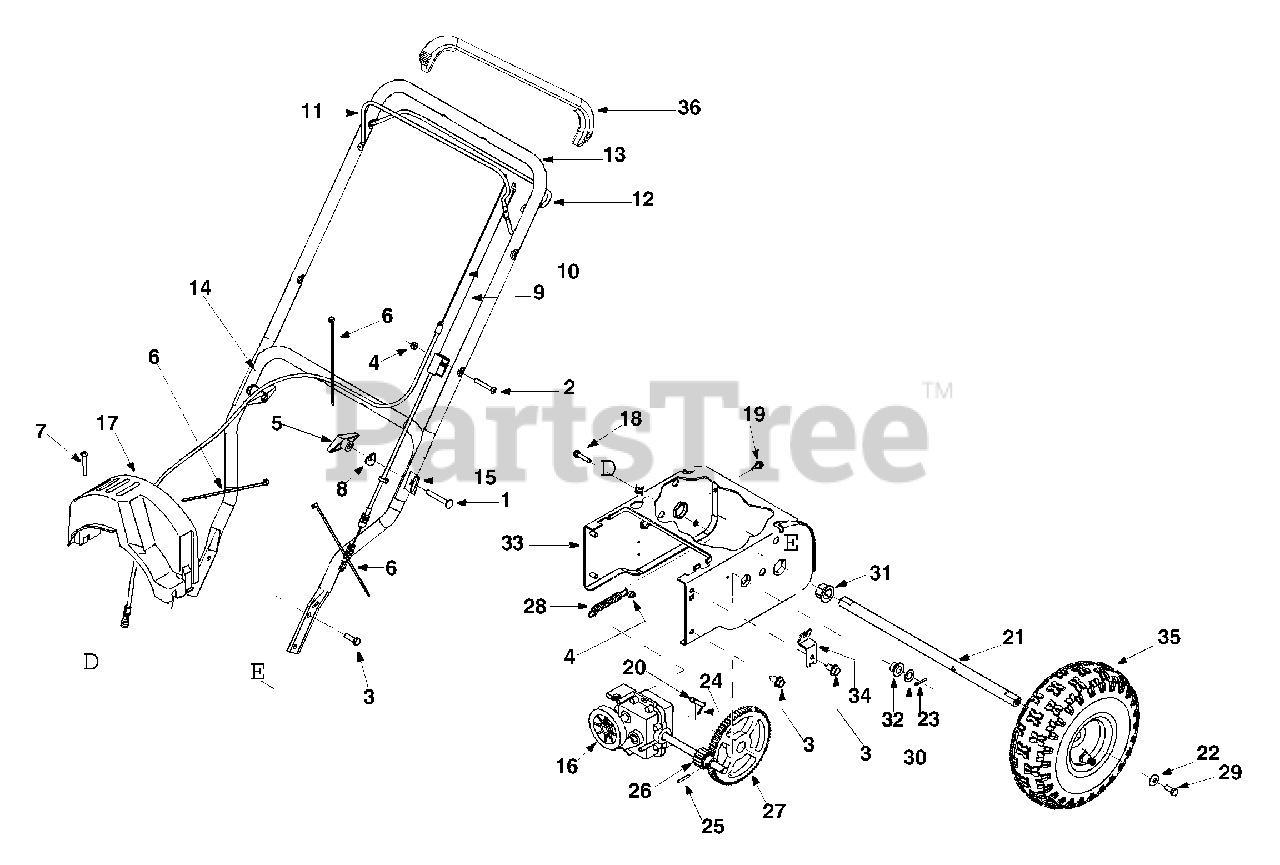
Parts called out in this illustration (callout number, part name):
1	Carriage Screw 5/16-18 x 2.25"
2	Mach. Screw 1/4-20 x 1.825"
3	Screw, 5/16-12 x.75"
4	Flange Lock Nut 1/4-20
5	Handle Knob Assembly
6	Cable Tie
7	Hex Screw, #10-16 x.500
8	Saddle Washer
9	Auger Cable
10	Drive Cable
12	Drive Control
15	Handle Tab
16	Transmission Assembly
16	Transmission Assembly Kit
17	Belt Cover
18	TT Screw 1/4-20 x 1.25"
19	Screw, 1/4-20 x.625"
20	Clevis Pin
21	Axle
22	Bell Washer
23	Cotter Pin, 1/8 x 1.0
24	Cotter Pin, 3/32 x.750
25	Roll Pin
26	Pinion 14T
27	Gear 70T
28	Extension Spring
29	Lock Bolt 5/16-24 x 0.75"
30	Flat Washer
31	Hex Flange Bearing
32	Hex Flange Bearing
36	Deluxe Bail Cover
